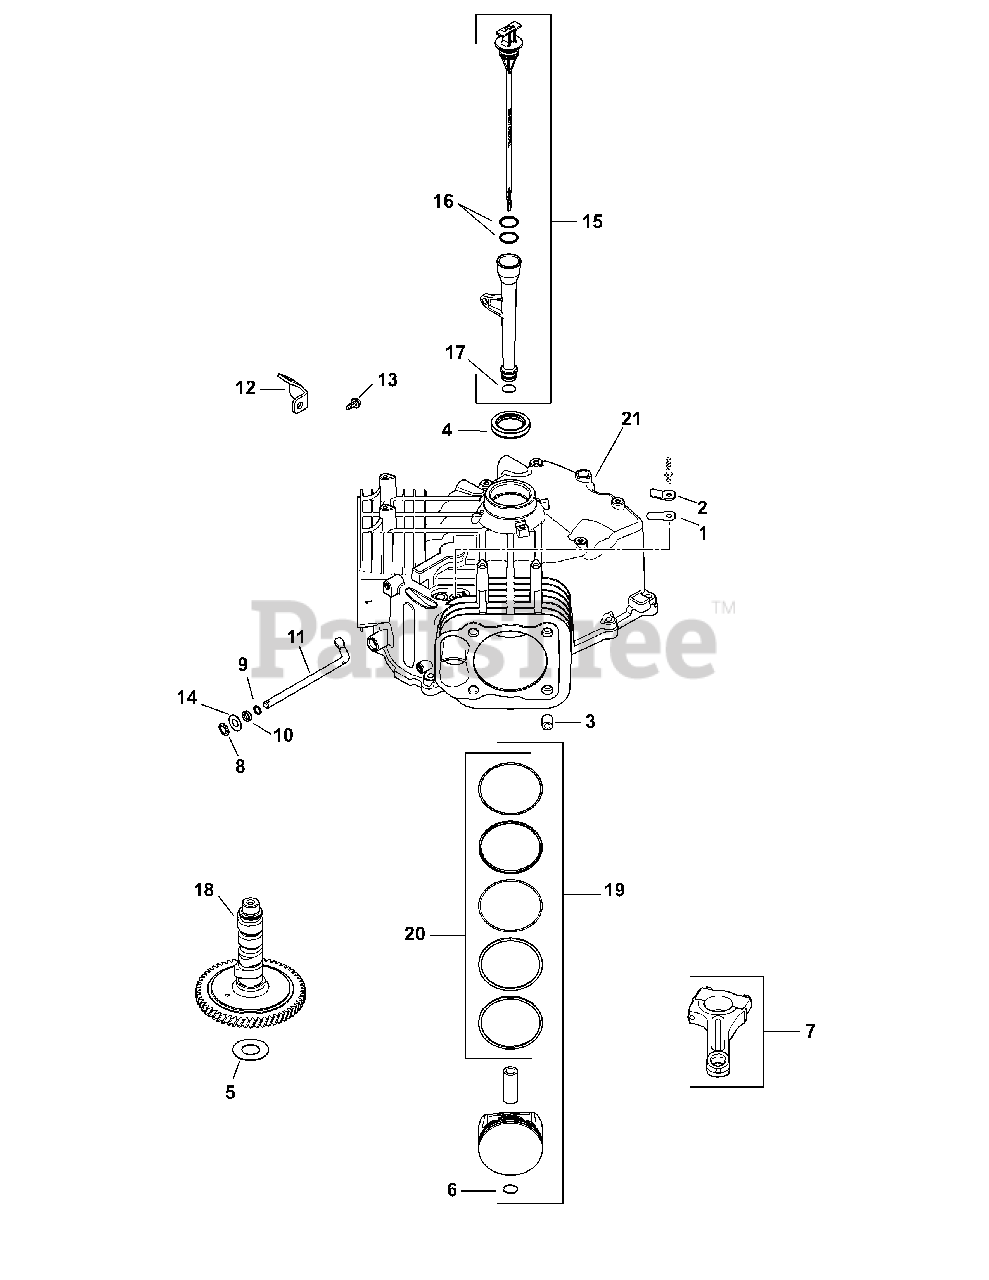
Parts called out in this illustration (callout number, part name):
1	Breather Reed
2	Breather Reed Retainer
4	Oil Seal, 1.78 x 1.26
5	Camshaft Shim (White, .028)
5	Camshaft Shim (Blue, .03)
5	Camshaft Shim (Red, .032)
5	Camshaft Shim (Yellow, .034)
5	Camshaft Shim (Green, .036)
5	Camshaft Shim (Gray, .038)
5	Camshaft Shim (Black, .04)
6	Piston Pin Retainer
7	Connecting Rod (STD)
8	Ring Retainer
9	Flat Washer, 11/32
10	Governor Cross Shaft Seal
11	Governor Cross Shaft
12	Oil Fill Tube Bracket
13	Flange Screw, M5 x .8 x 13
14	Flat Washer, 9mm
15	Dipstick & Tube Kit
17	Lower Oil Fill Tube O-Ring
18	Camshaft Assembly
19	Piston Kit w/ Ring
19	Piston Kit w/ Ring (0.25) 83mm
19	Piston Kit w/ Ring (0.08) 83mm
20	Ring Set, Piston STD
20	Ring Set, Piston (.08)
20	Ring Set, Piston (.25)
21	Crankcase (Use Short Block)
